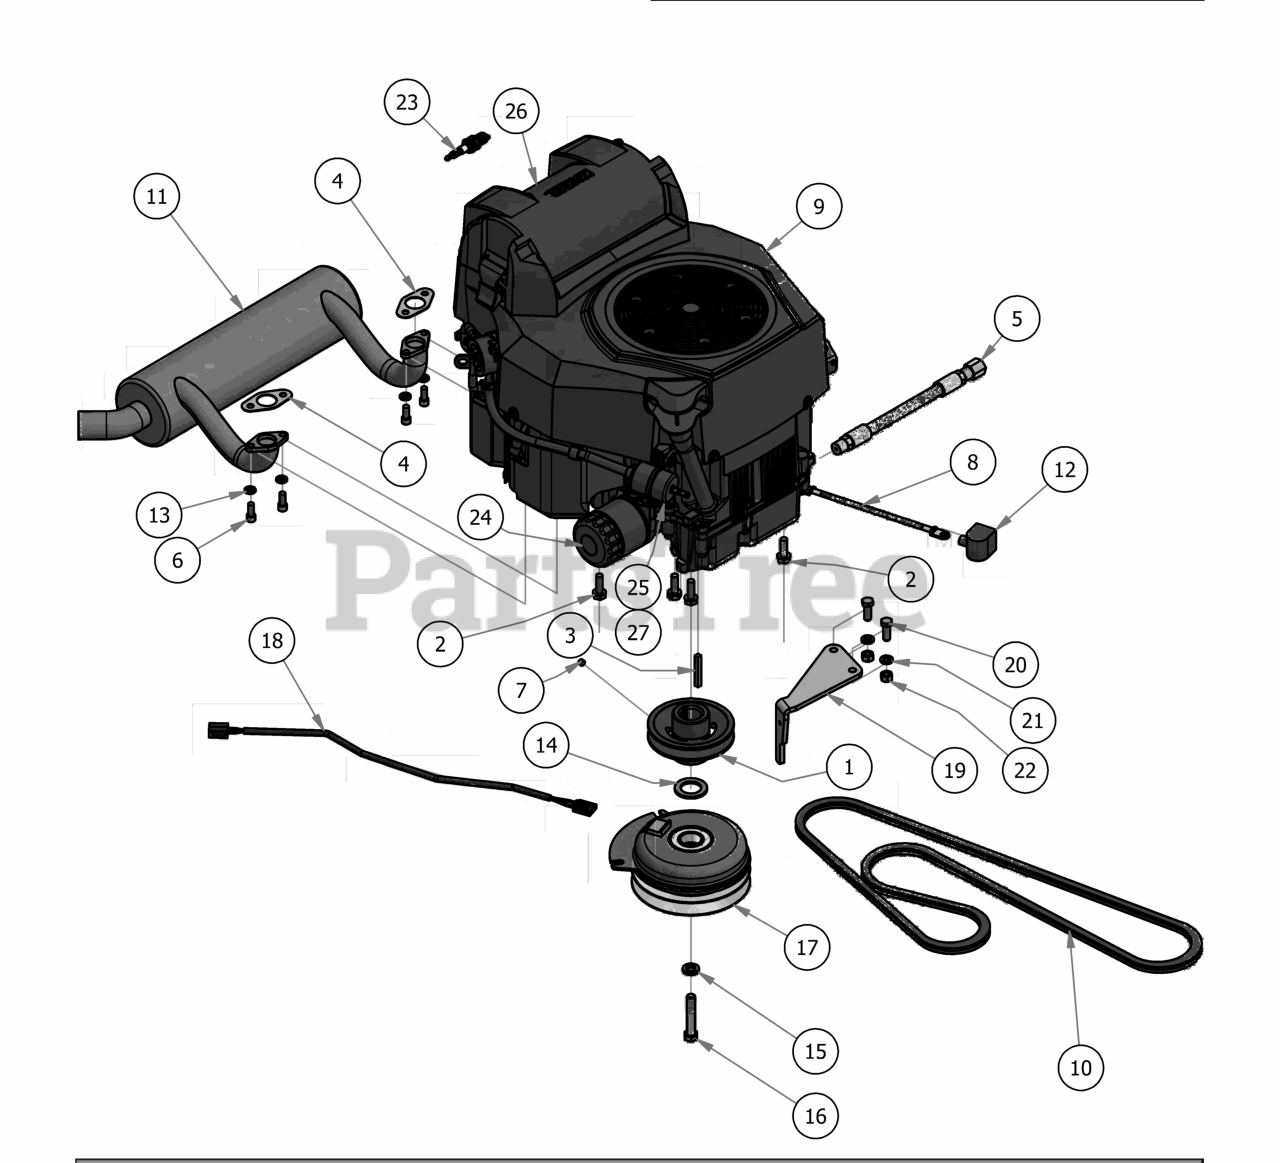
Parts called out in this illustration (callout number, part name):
1	4 3/4 Motor Pulley
2	3/8 x 1 1/8 bolt
3	1/4 x 2 Square key Stock
4	Exhaust Gasket
5	Oil drain Valve
6	5/16-18 x 3/4 Socket C/S
7	5/16 Set Screw
8	Ground Cable
9	Kohler-2014 CZT/Outlaw 747cc
11	2014 Kohler Outlaw Muffler
12	Black Boot For Ground Cable
13	5/16" Lock Washer
14	1 1/8" Flat Spacer
15	7/16" Lock Washer
16	7/16" x 2 1/2" Hex Bolt
17	Clutch Assembly
18	Clutch Pigtail
19	PTO Engager Holder
20	3/8" x 1" Hex Bolt
21	3/8" Lock Washer
22	3/8" Hex Nut
23	Spark Plug
24	725 & 747 Kohler Oil Filter
25	Universal Inline Fuel Filter
26	747 Kohler Air Filter
27	Kohler Fuel Filter
